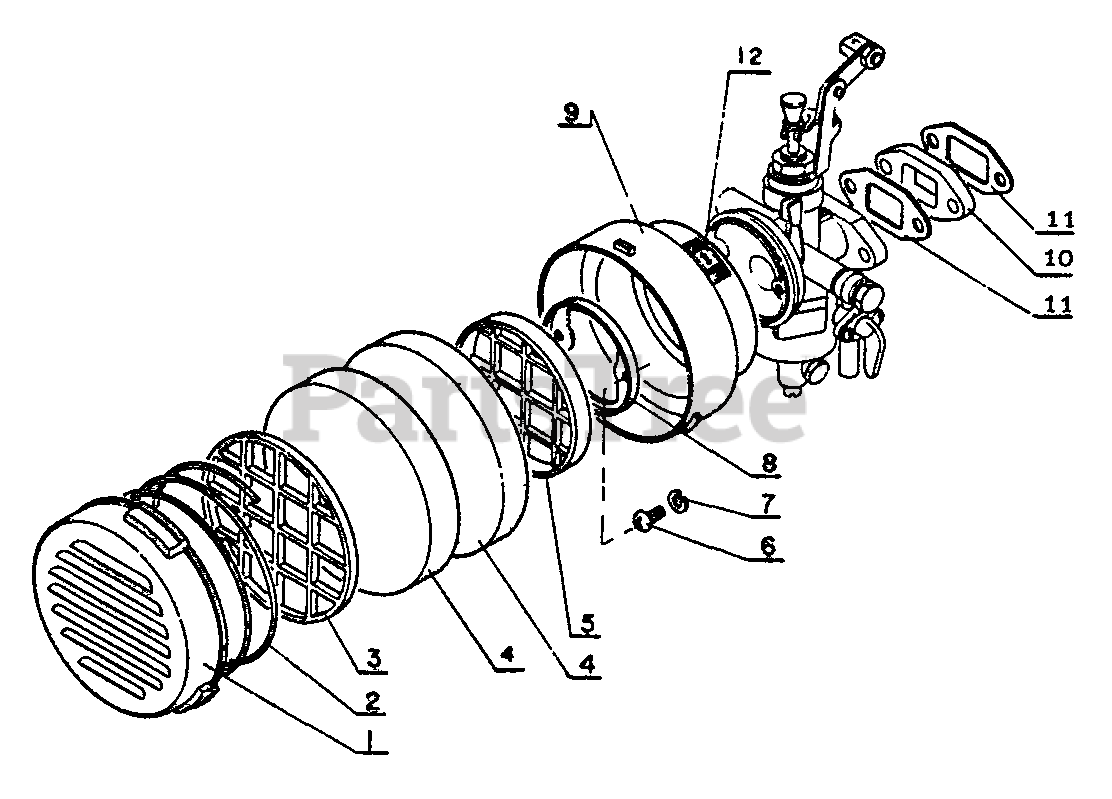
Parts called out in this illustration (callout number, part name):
1	COVER, AIR FILTER
2	SPRING, AIR FILTER COVER
3	HOLDER, AIR FILTER
4	FILTER, AIR
5	GRID, AIR FILTER
6	SCREW 4×12
7	WASHER, SPRING 4 MM
8	BRACKET, AIR FILTER
9	CASE, AIR FILTER
10	INSULATOR
12	LABEL - CHOKE
